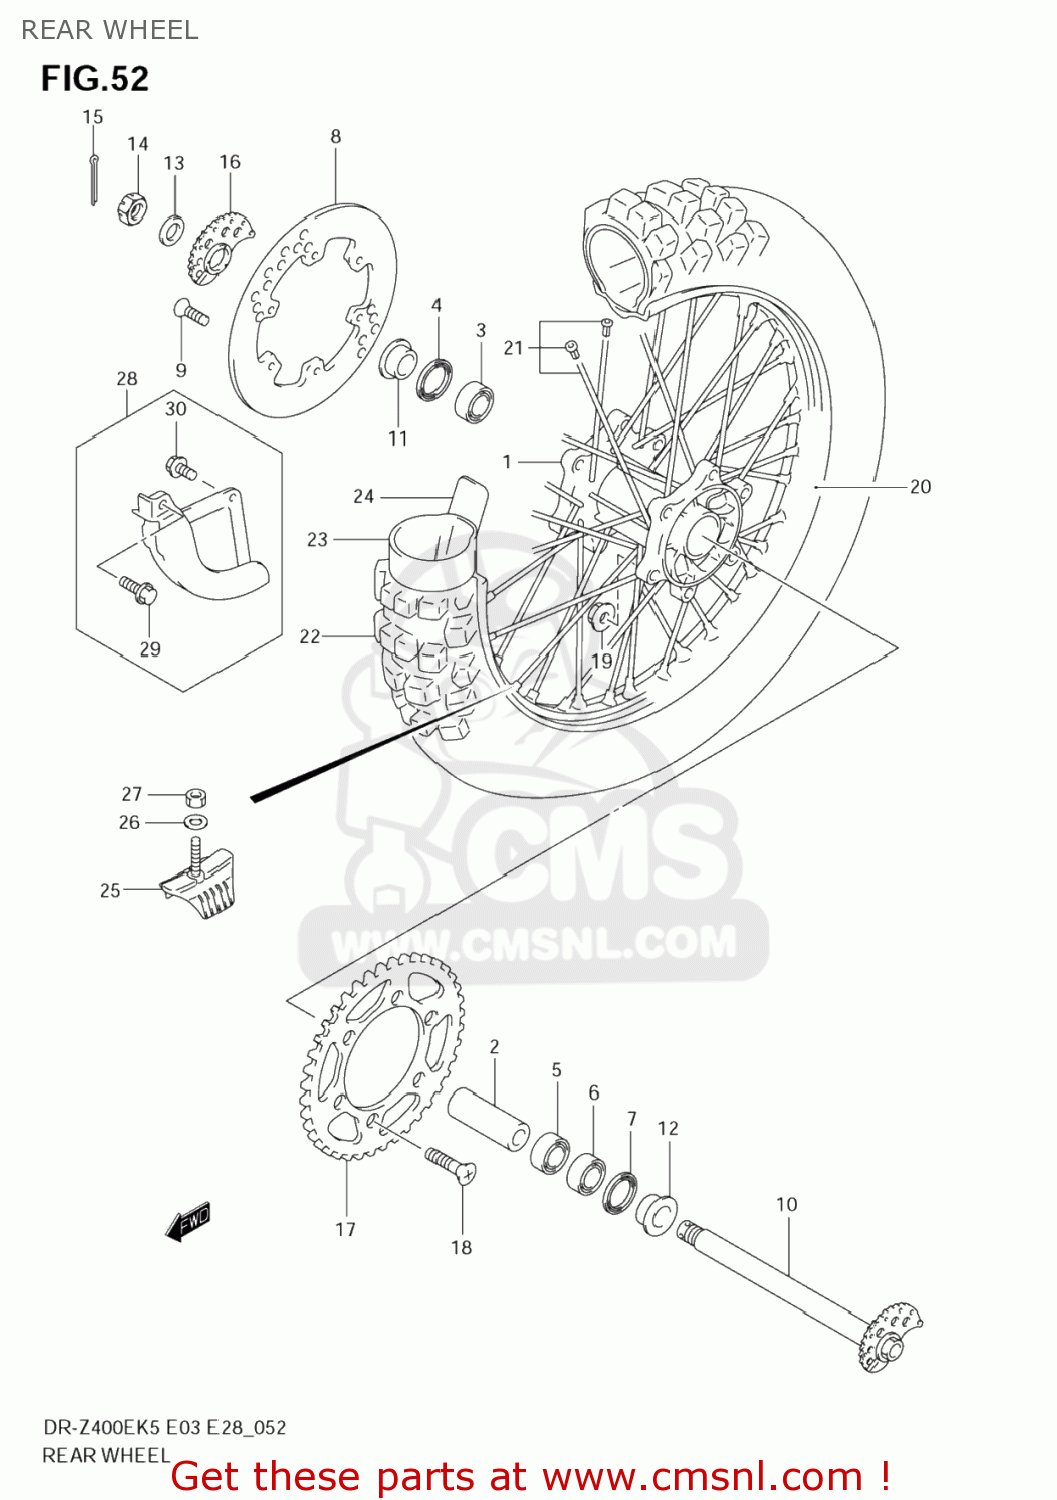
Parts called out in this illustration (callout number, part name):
1	HUB,RR WHEEL
2	SPACER,RR HUB BEARING
3	BEARING
4	SEAL(29X42X6)
5	BEARING
6	BEARING
7	SEAL,OIL(29X47X6)
8	DISC,RR BRAKE
9	SCREW
10	AXLE,RR
11	SPACER,RR AXLE
12	SPACER,RR AXLE
13	WASHER(19X32X3.2)
14	NUT
15	PIN,COTTER
16	ADJUSTER,CHAIN,R
17	SPROCKET,RR(NT:47-520)
18	BOLT(8X30.5)
19	NUT
20	RIM,RR WHEEL(18X2.15 AL)
21	SPOKE SET,RR WHEEL
22	TIRE,RR(110/100 18 64M)
23	TUBE ASSY,WHEEL INNER
24	PROTECTOR,WHL INR TUBE
25	STOPPER,BEAD(2.15)
26	WASHER
27	NUT
28	COVER SET,RR BRAKE DISC
29	BOLT
30	BOLT
